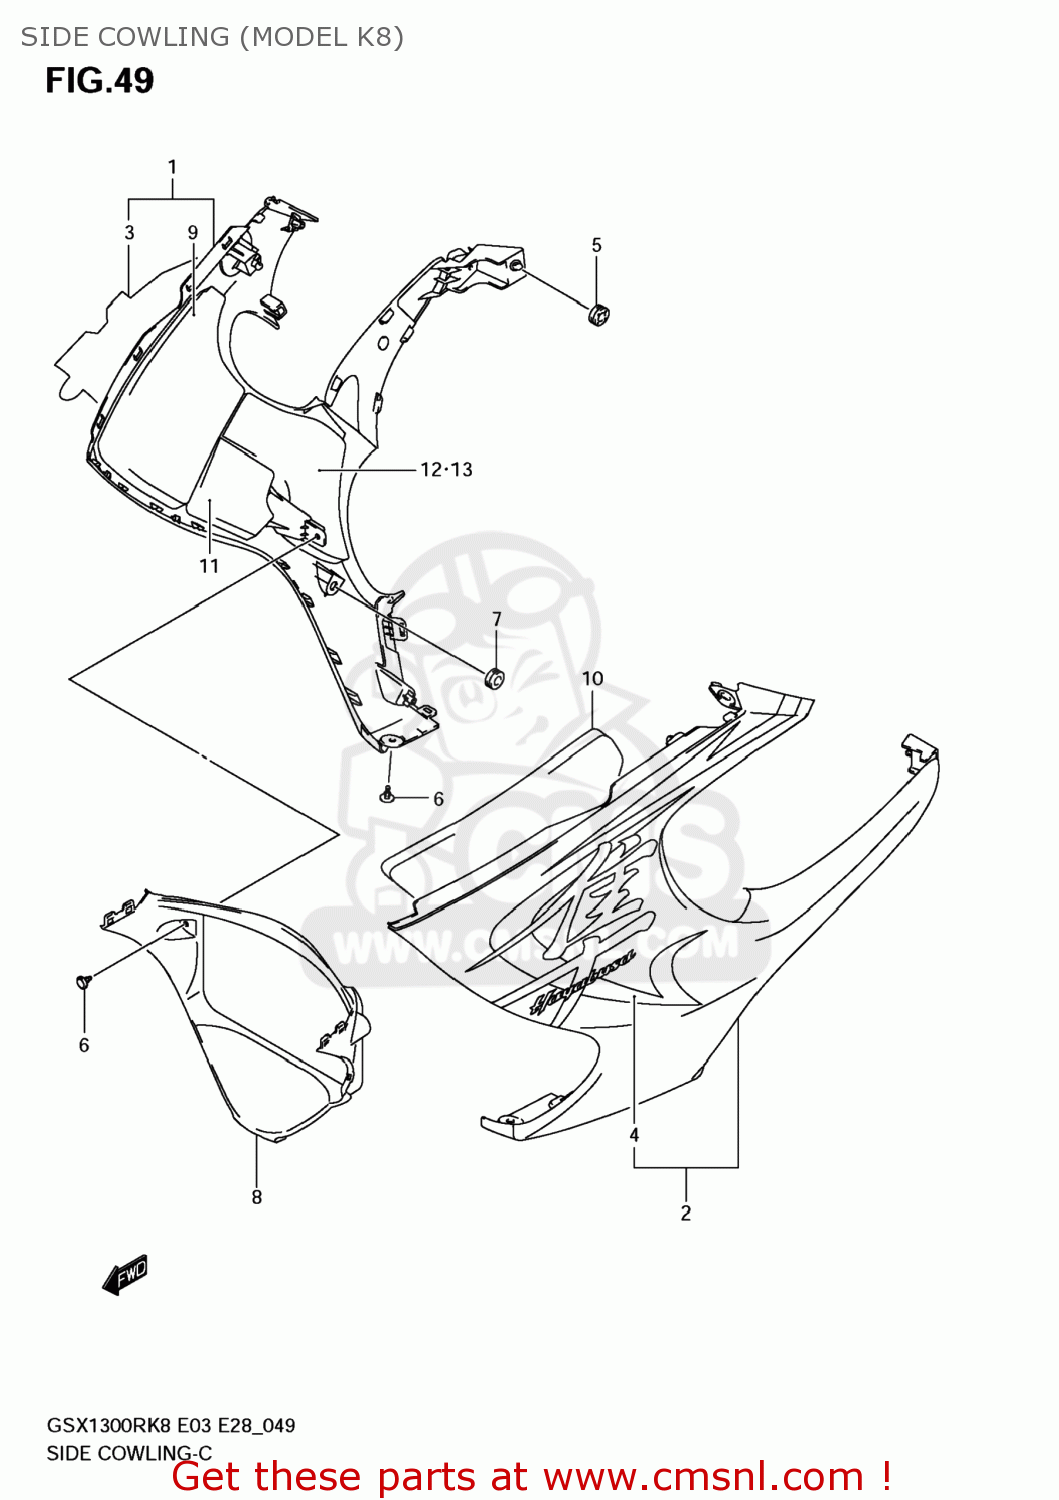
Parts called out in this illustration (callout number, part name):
1	COWLING COMP,S
2	COWLING COMP,S
3	TAPE SET,COWL SIDE,R
4	TAPE SET,COWL SIDE,L
5	CUSHION
6	CLIP
7	CUSHION
8	COWLING,UNDER CTR
9	CUSHION,SIDE COWL,R
10	CUSHION,SIDE COWL,L
11	CUSHION,SIDE COWL
12	SHIELD,SIDE COWL,R
13	SHIELD,SIDE COWL,L
